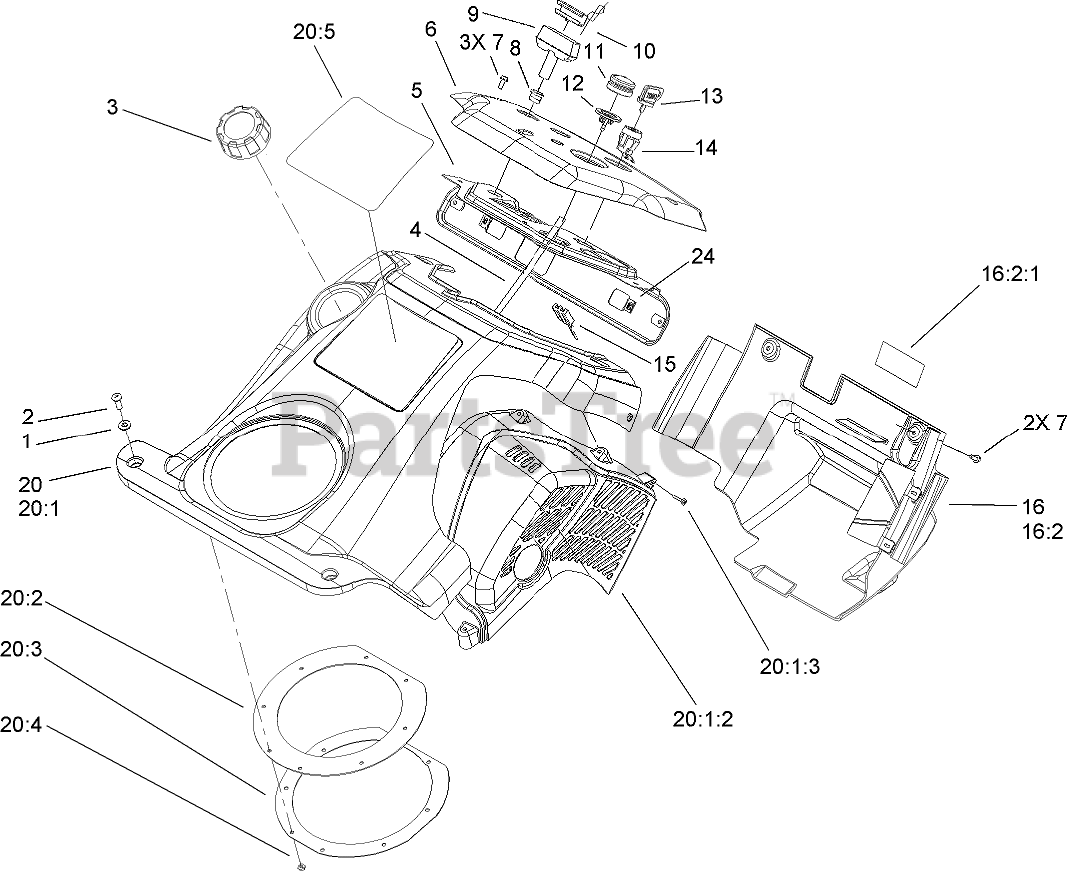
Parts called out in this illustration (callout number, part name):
1	WASHER-FLAT
2	SCREW-PPH
3	GAS CAP ASM
4	HOSE-PRIMER
5	PANEL-SUPPORT, CONTROL
6	PANEL-CONTROL
7	SCREW-HWH
8	GUIDE-ROPE, STARTER
9	HANDLE-START
10	CLIP-STARTER
11	BULB-PRIMER
12	BODY-PRIMER
13	KEY-IGNITION
14	SWITCH
15	CONNECTOR-BODY
16	LOWER SHROUD AND BAFFLE ASM
16:2	SHROUD-LOWER
16:2:1	DECAL
20	UPPER SHROUD ASM
20:1	SHROUD-UPPER
20:1:2	SHIELD-HEAT
20:1:3	SCREW-PPH
20:2	Seal-Chute
20:3	RETAINER-SEAL, CHUTE
20:4	PALNUT
24	NUT-SPEED
